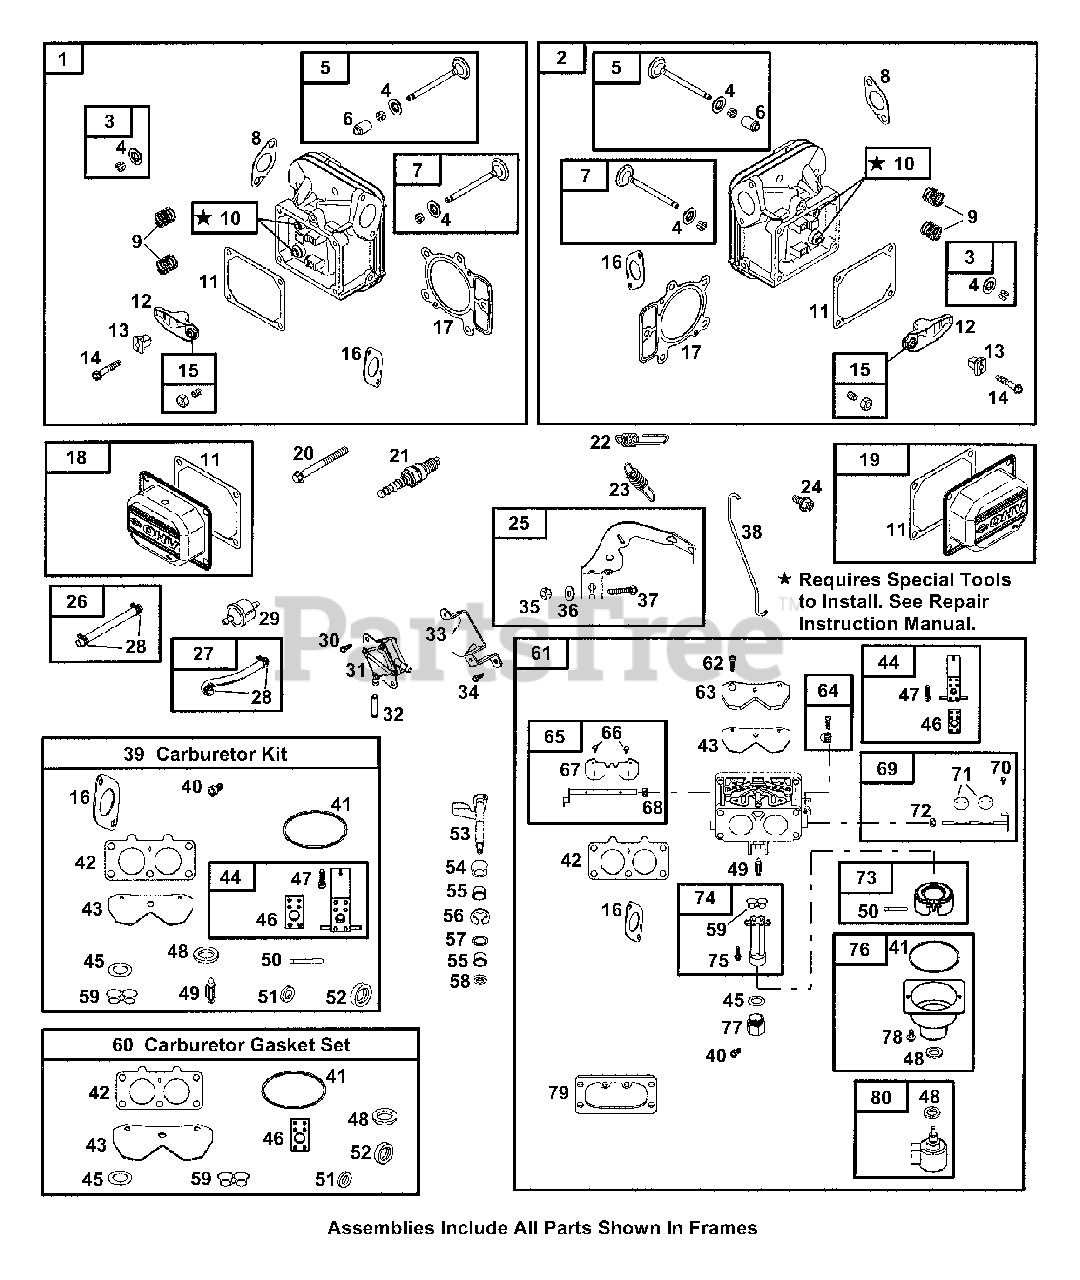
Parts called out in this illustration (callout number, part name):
1	Cylinder Head (Cylinder #1)
2	Cylinder Head (Cylinder #2)
3	Valve Keeper
4	Valve Retainer
5	Intake Valve
6	Valve Seal
7	Exhaust Valve
8	Exhaust Gasket
9	Valve Spring
10	Guide Bushing
11	Rocker Cover Gasket
12	Rocker Arm
13	Rocker Arm Pivot
14	Screw (Rocker Arm)
15	Rocker Arm Adjuster
16	Intake Gasket
17	Cylinder Head Gasket
18	Cover-Rocker (Cylinder #1)
19	Cover-Rocker (Cylinder #2)
20	Screw (Cylinder Head)
21	Sparkplug
22	Governed Idle Spring
23	Governor Spring
24	Screw (Rocker Cover)
25	Governor Control Lever
26	Fuel Line (Cut to Required Length)
27	Fuel Line (Molded)
28	Hose Clamp
29	Fuel Filter
30	Screw (Fuel Pump)
31	Fuel Pump
32	Vacuum Hose
33	Fuel Pump Bracket
34	Screw (Fuel Pump Bracket)
35	Nut (Governor Control Lever)
36	Washer (Governor Control Lever)
37	Bolt (Governor Control Lever)
38	Throttle Link
39	Carburetor Kit
41	Float Bowl Gasket
42	Intake Gasket
43	Carburetor Cover Plate Gasket
44	Carburetor Nozzle
45	Cover-Rocker (Cylinder #1)
46	Nozzle Gasket
47	Screw (Carburetor Nozzle)
48	Sealing Washer
49	Float Needle Valve
50	Float Hinge Pin
51	Choke Shaft Seal
52	Throttle Shaft Seal
53	Governor Crank
54	Governor Crank Bushing
55	Governor Crank Bushing
56	E-Ring Retainer
57	Washer (Governor Crank)
58	Governor Shaft Seal
59	O-Ring Seal (Fuel Transfer Tube)
60	Carburetor Gasket Set
61	Carburetor
62	Screw (Cover Plate)
63	Cover Plate
64	Idle Speed Kit
65	Choke Shaft Kit
66	Screw (Choke Shaft)
67	Choke Valve
68	Choke Shaft Seal
69	Throttle Shaft Kit
70	Screw (Throttle Valve)
71	Throttle Valve
72	Throttle Shaft Seal
73	Carburetor Float
74	Fuel Transfer Tube
75	Screw (Fuel Transfer Tube)
76	Float Bowl
77	Solenoid Retainer
78	Screw (Float Bowl)
79	Air Cleaner Gasket
80	Fuel Solenoid
